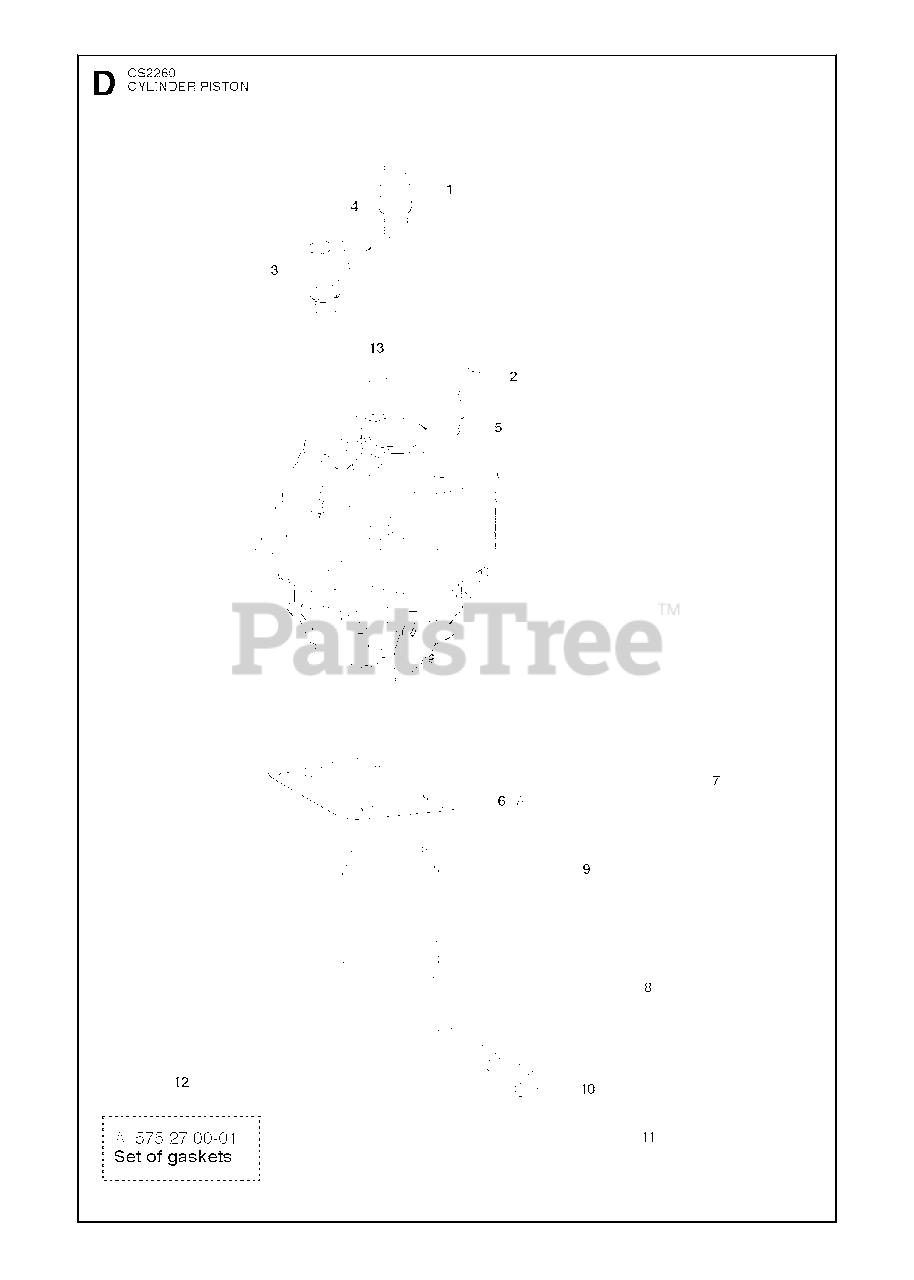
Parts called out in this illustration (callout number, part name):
1	CMR6H SPARK PLUG NGK
2	SCREW MC6S 5X35
3	DECOMPRESSION VALVE
4	CYLINDER PLUG
6	GASKET
7	CYLINDER ASSY
8	PISTON ASSY
9	PISTON RING
10	LOCKING RING
11	NEEDLE BEARING
12	GASKET KIT
13	BUSHING
